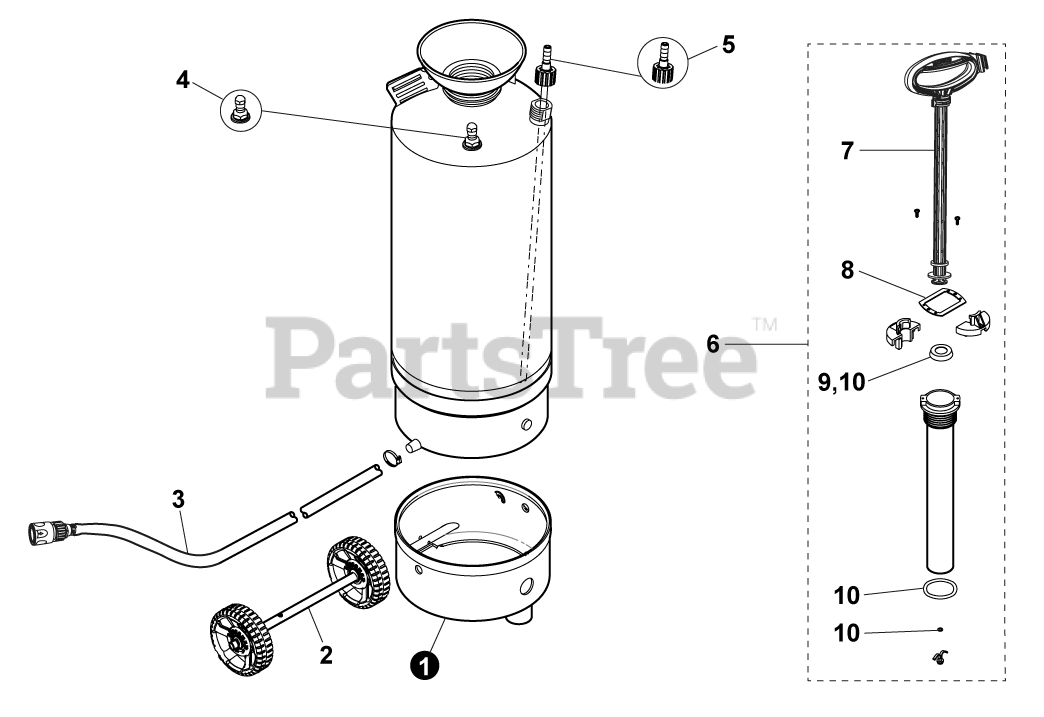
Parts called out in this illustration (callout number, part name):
1	TANK BASE W/SUPPORT
2	SET, WHEEL W/AXLE
3	HOSE, FLEXIBLE W/ GRIP
4	VALVE, SCHRADER
5	PRESSURE RELIEF VALVE
6	TUBE, PUMP
7	HANDLE, PUMP
8	CAPS, PUMP TUBE
9	PISTON, PLASTIC
10	KIT, PUMP REPAIR
